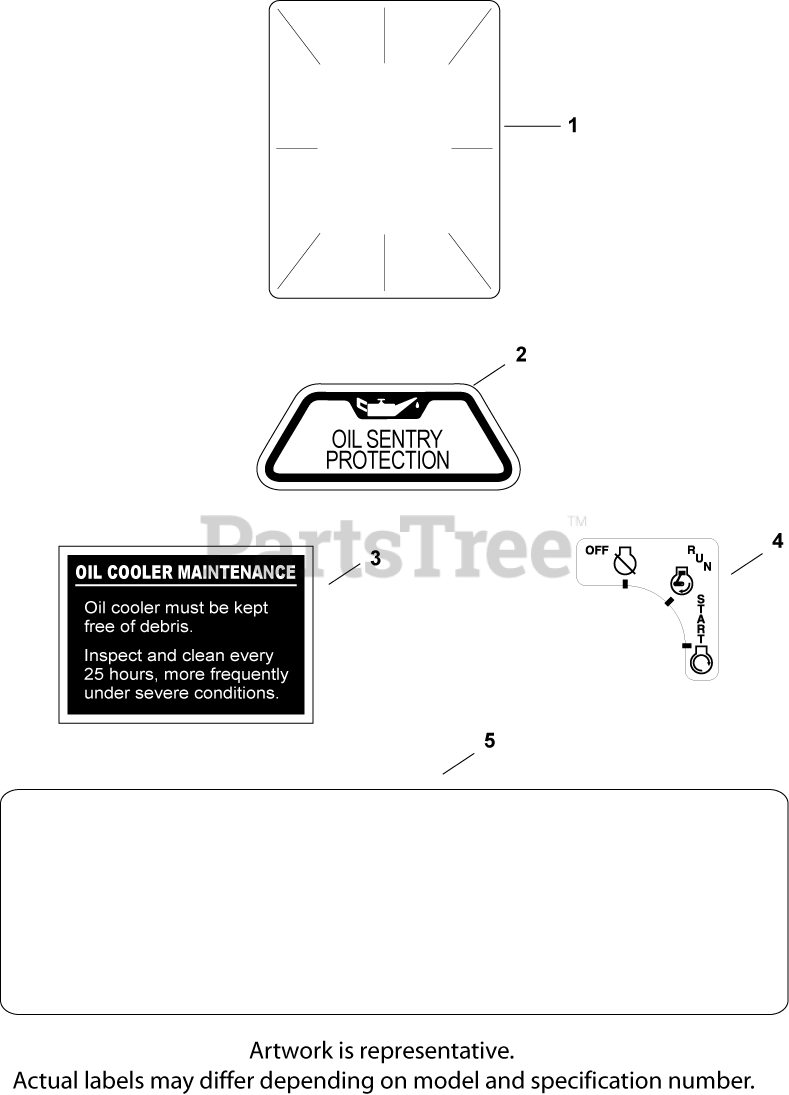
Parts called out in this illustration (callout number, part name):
1	DECAL, CLEAR LAMINATE USE 25 113 70-S
2	DECAL, OIL SENTRY - (#DSC)
3	DECAL, OIL COOLER - (#DSC)
4	DECAL, KEY SWITCH
5	DECAL, 18 HP
